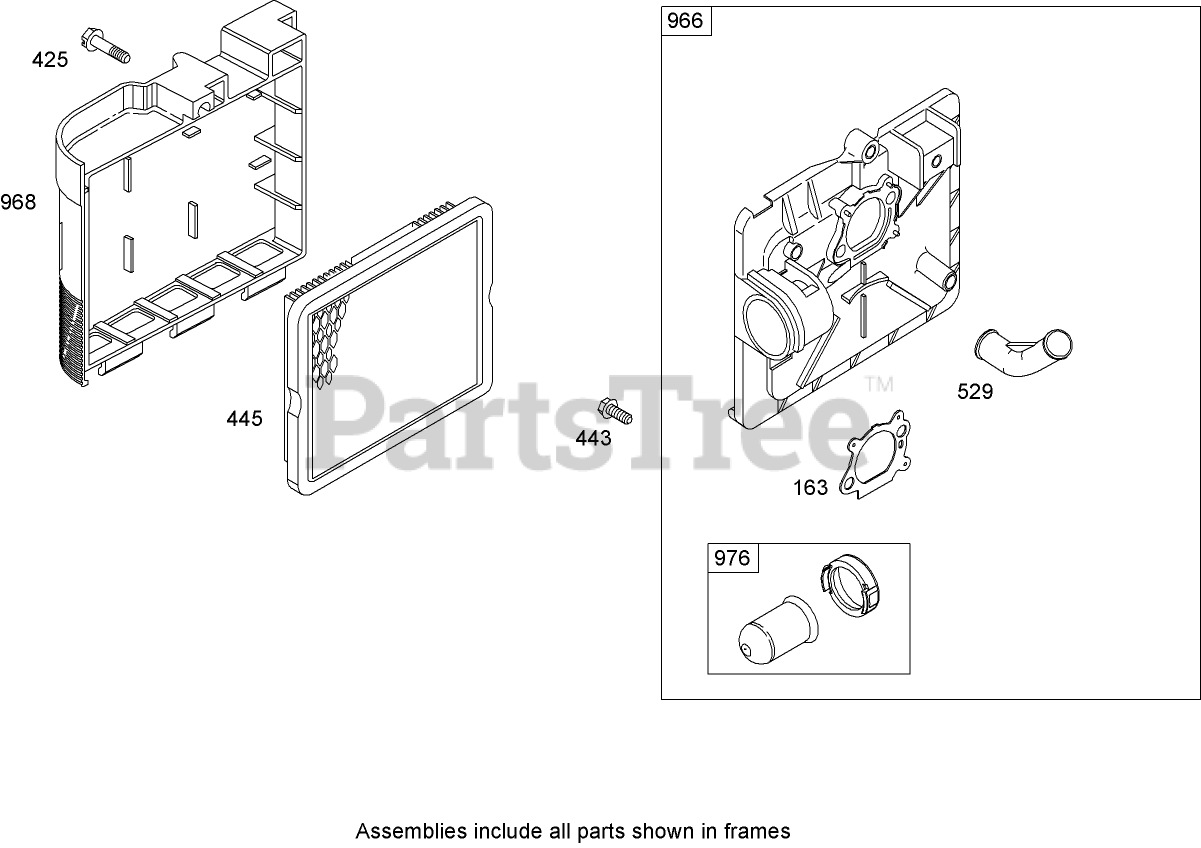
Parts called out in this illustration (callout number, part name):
163	Gasket-Cleaner, Air
425	Screw
443	Screw
445	Filter-Cartridge, Air Cleaner
529	Grommet
966	Base-Primer, Air Cleaner
968	Cover-Cleaner, Air
976	Primer-Carburetor
